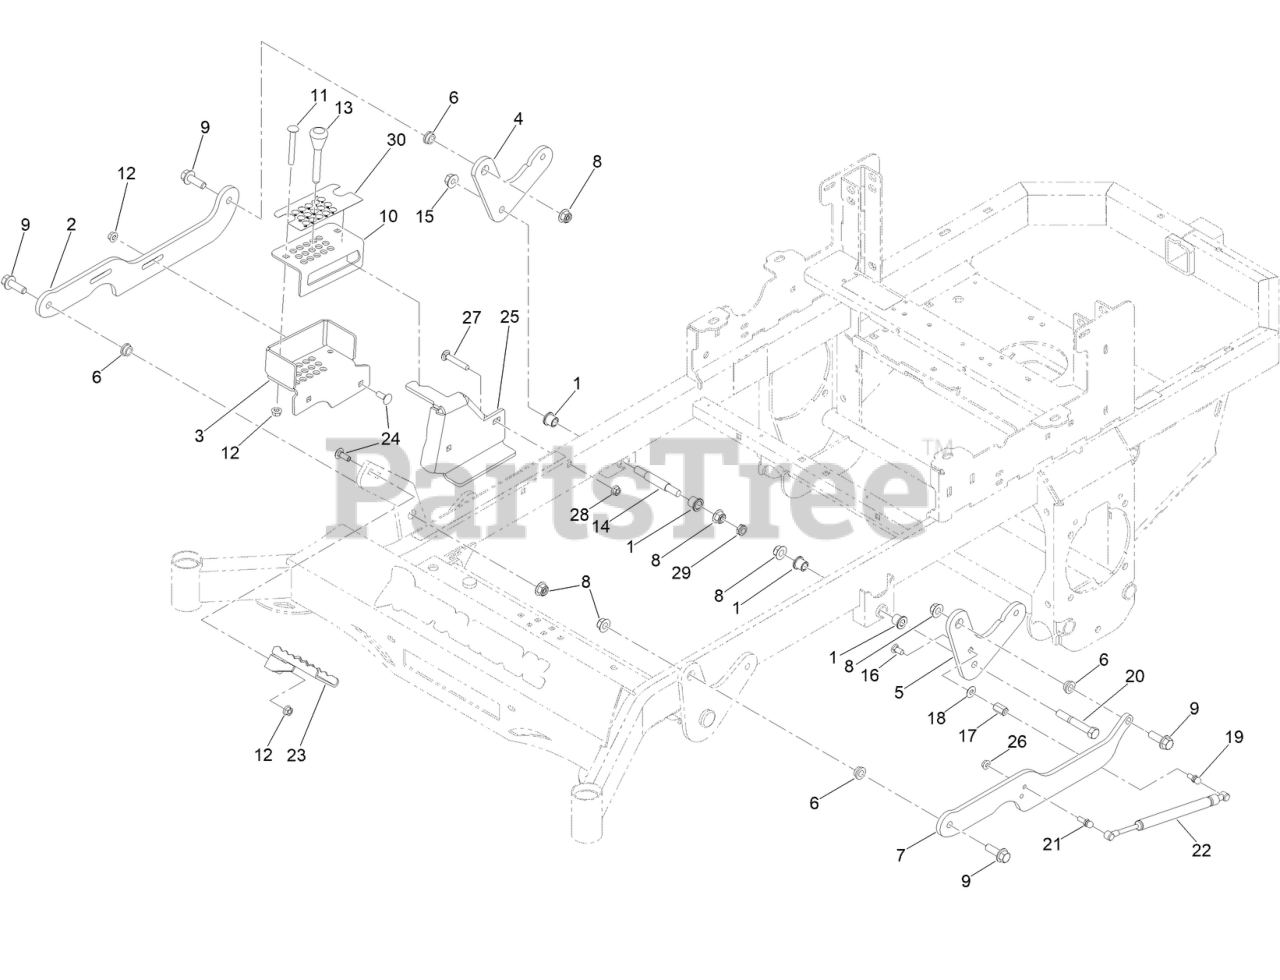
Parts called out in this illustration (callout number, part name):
1	BUSHING-FLANGE
2	2024 DECK HGHT ARM RT LINK
3	2022 DHI PIN ARM LINK BOTTOM BRACKET
4	ARM-DECKLIFT REAR (3/8")
5	ARM-DECKLIFT REAR (3/8")
6	1/2IN ID X 3/4IN OD X 3/8IN FLANGE BUSH
7	LINK-DECKLIFT
8	1/2-13 HEX FLANGE 2-WAY REV CNTR L/NYZ
9	SCREW-HHF
10	2022 DHI PIN ARM LINK TOP BRKT BLACK
11	(3/8-16 X 3 CARRIAGE BOLT (GR.5) ZC/YEL)
13	MAGNETIC PIN FOR STAND ON MWR
14	RR DECK HEIGHT BOLT (MACHINED)
15	NUT-HHF
16	3/8 X 3/4IN GR 8 CARR BOLT ZINC
17	HEX COUPLING NUT - REDUCER (3/8" TO 5/16
18	5/16IN USS FLAT WASHER (3/8 ID X 7/8 OD)
19	5/16-18X1.286 DAMPER BALL STUD (.562 TL)
20	1/2-13 X 3-1/2 HEX C/S GR 5 ZINC YELLOW
21	5/16-18X1.286 DAMPER BALL STUD (.562 TL)
22	DECK ASSIST GAS SPRING
23	MWR DECK HEIGHT FOOT PEDAL BLACK
24	3/8-16 X 1 CARRIAGE BOLT YZ GR.8
25	2022 DECK LOCK PIN TUBE BRKT BLACK
27	SCREW-CARR
28	3/8-16 HEX FLANGE NUT W/SERR ZINC YELLOW
29	NUT-HEX
30	DECAL-HEIGHT OF CUT
